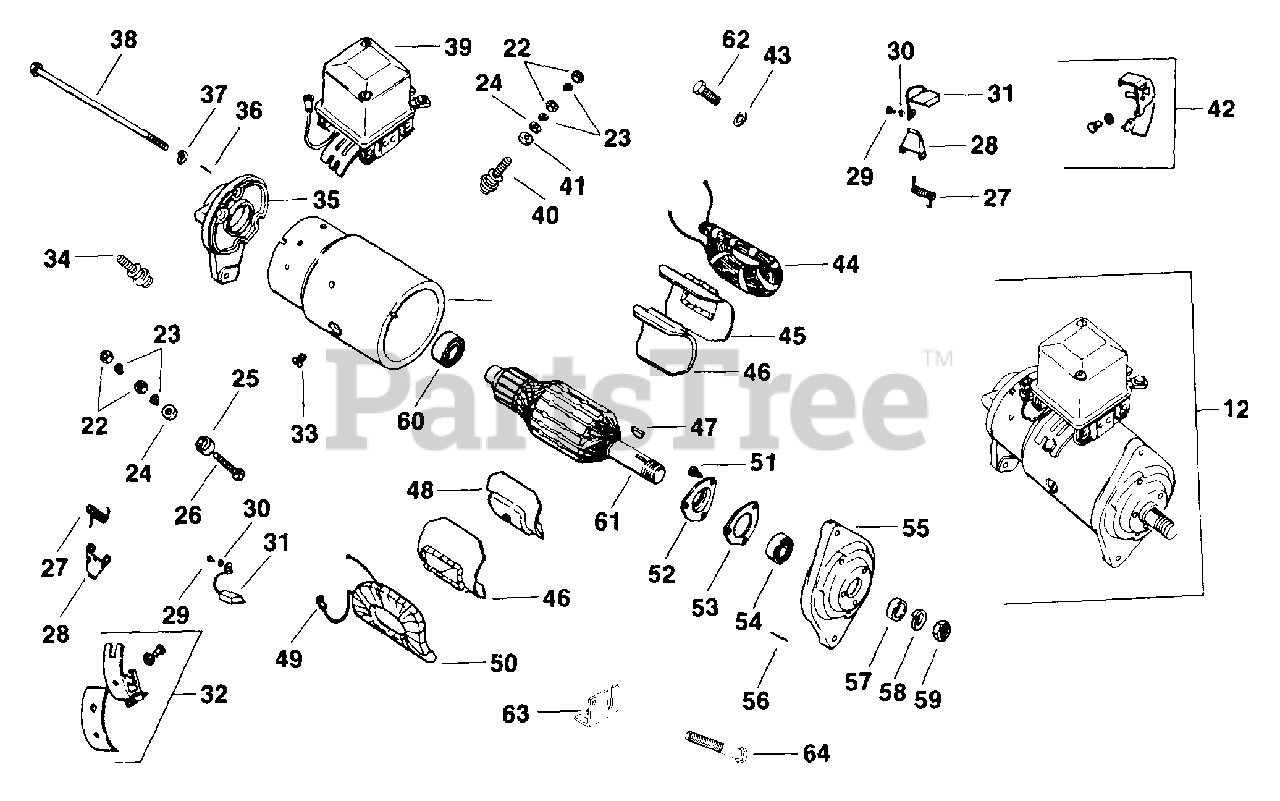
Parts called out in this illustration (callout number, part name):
22	NUT - DISCONTINUED
29	SCREW, SLT PAN HD 6-32X5/16" USE 25 086 57-S
31	BRUSH - DISCONTINUED
32	HOLDER - DISCONTINUED
33	SCREW - DISCONTINUED
36	PIN - DISCONTINUED
41	WASHER - DISCONTINUED
42	HOLDER - DISCONTINUED
47	KEY - USE X-43-3
51	SCREW - DISCONTINUED
53	GASKET - DISCONTINUED
54	BEARING - DISCONTINUED
56	PIN - DISCONTINUED
61	ARMATURE - DISCONTINUED
